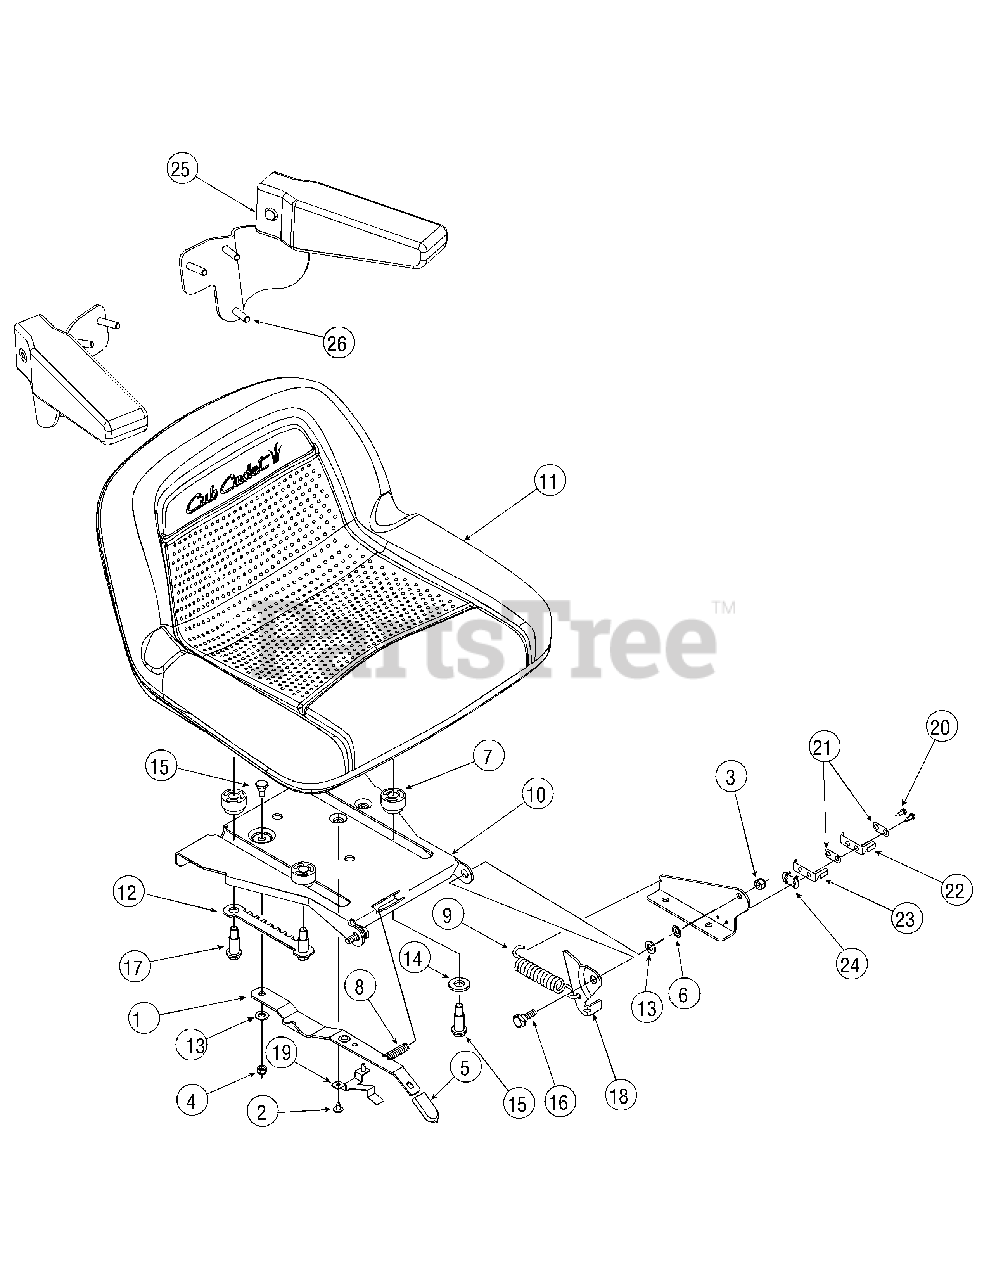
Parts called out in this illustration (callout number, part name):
2	Screw, #10-16, 0.375
3	Nut, Nylon Lock, 5/16-18, Gr5
4	Nut, Nylon Lock, 1/4-20
5	Grip, Seat, Adjustment (Yellow)
6	Nut, Speed, .3125 ID
7	Spacer, Seat, Adjustment
8	Spring, Compression .41 OD x 1.50
9	Spring, Extension, .80 Dia x 4.6
12	Selector, Seat, Adjustment
13	Washer, Flat, .344 x .688 x .065
14	Washer, Flat, .531 x 1.062 x .134
15	Screw, Shoulder, .340 x .285, 1/4-
16	Shoulder, Screw .437 x .286 Lg
17	Screw, Shoulder, .50 x.925, 3/8-16
18	LH Bracket, Seat Lift
18	RH Bracket, Seat Lift
19	Stop, Seat, Adjustment
20	Screw, #8-18 x .50
21	Plate, Insulator
22	Spring Switch, Inner
23	Spring Switch, Outer
24	Plate, Insulator Boss
25	Armrests (Includes two armrests)
26	Screw, 5/16-18, .75
